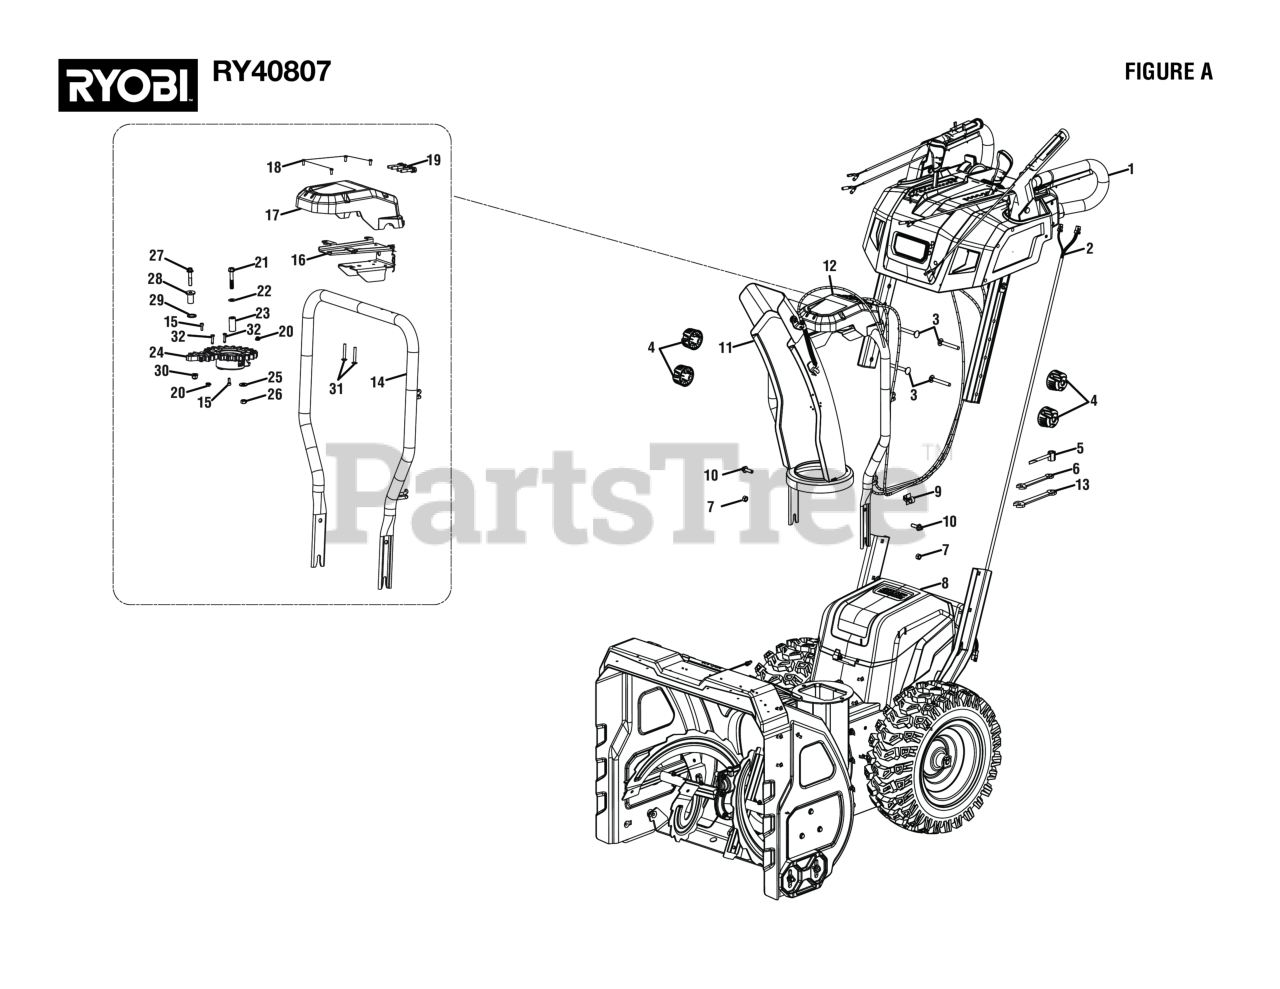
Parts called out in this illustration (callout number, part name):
1	Upper Handle Assembly
2	Electrical Wire Assembly
3	Carriage Bolt (M8 x 1.25 in.)
4	Knuckle Knob
6	Open Ended Wrench
7	Hex Nut (M8)
8	Down Body Assembly
9	Line Buckle
10	Screw (M8 x 25 mm)
11	Chute Assembly
12	Defletor Rotation Support Assembly
13	12 mm Wrench
14	Defletor Rotation Support Tube
15	Bolt (M5 x 14 mm)
16	Chute Rotation Bracket
17	Defletor Gear Cover
18	Screw (M4 x 10 mm, Pan Hd.)
19	Screw with Spring Washer (M6 x 35 mm)
20	Flange Lock Nut (M5 x 0.8 in.)
21	Bolt (M8 x 50 mm Hex Hd)
22	Washer (ID8.4 x OD18 x 1t)
23	Pivot Spacer
24	Cable Drum Assembly
25	Washer (ID8.5 x OD20.5 x 2 mm x 2t)
26	Hex Nut (M8)
27	Bolt (M8 x 1.25 x 40 mm, Flange Hd.)
29	Washer (ID 17.5 x OD24 x 1t)
30	Lock Nut (M8 x 1.25 mm, Flange)
31	Screw (M5 x 35 mm, T25 Torx Pan Hd.)
32	Screw (M4 x 18 mm, T20 Torx Pan Hd. S.T.)
